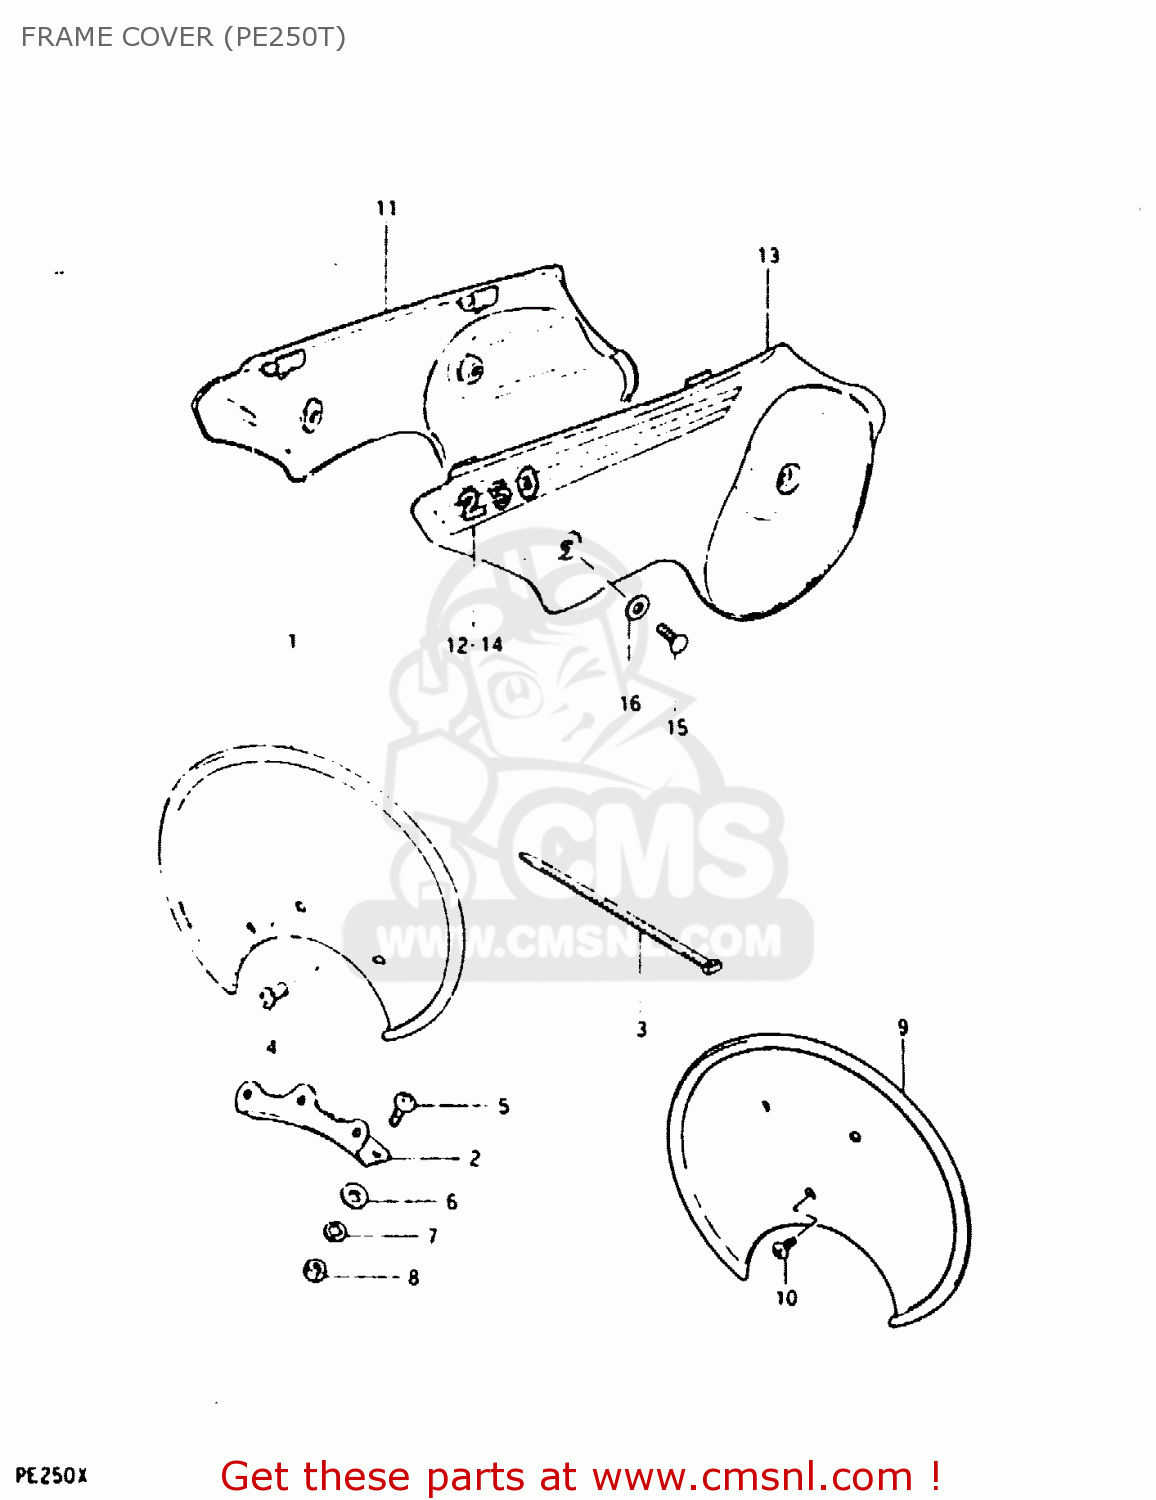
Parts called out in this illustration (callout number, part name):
1	PLATE,NUMBER,FRONT
2	BRACKET
3	CLAMP
4	SCREW
5	SCREW
6	WASHER
7	LOCK WASHER
8	NUT
11	COVER,FRAME,R(YELLOW)
12	TAPE,FRAME COVER,RIGHT
13	COVER,FRAME,L(YELLOW)
14	TAPE,FRAME COVER
15	SCREW 6X12
16	WASHER
